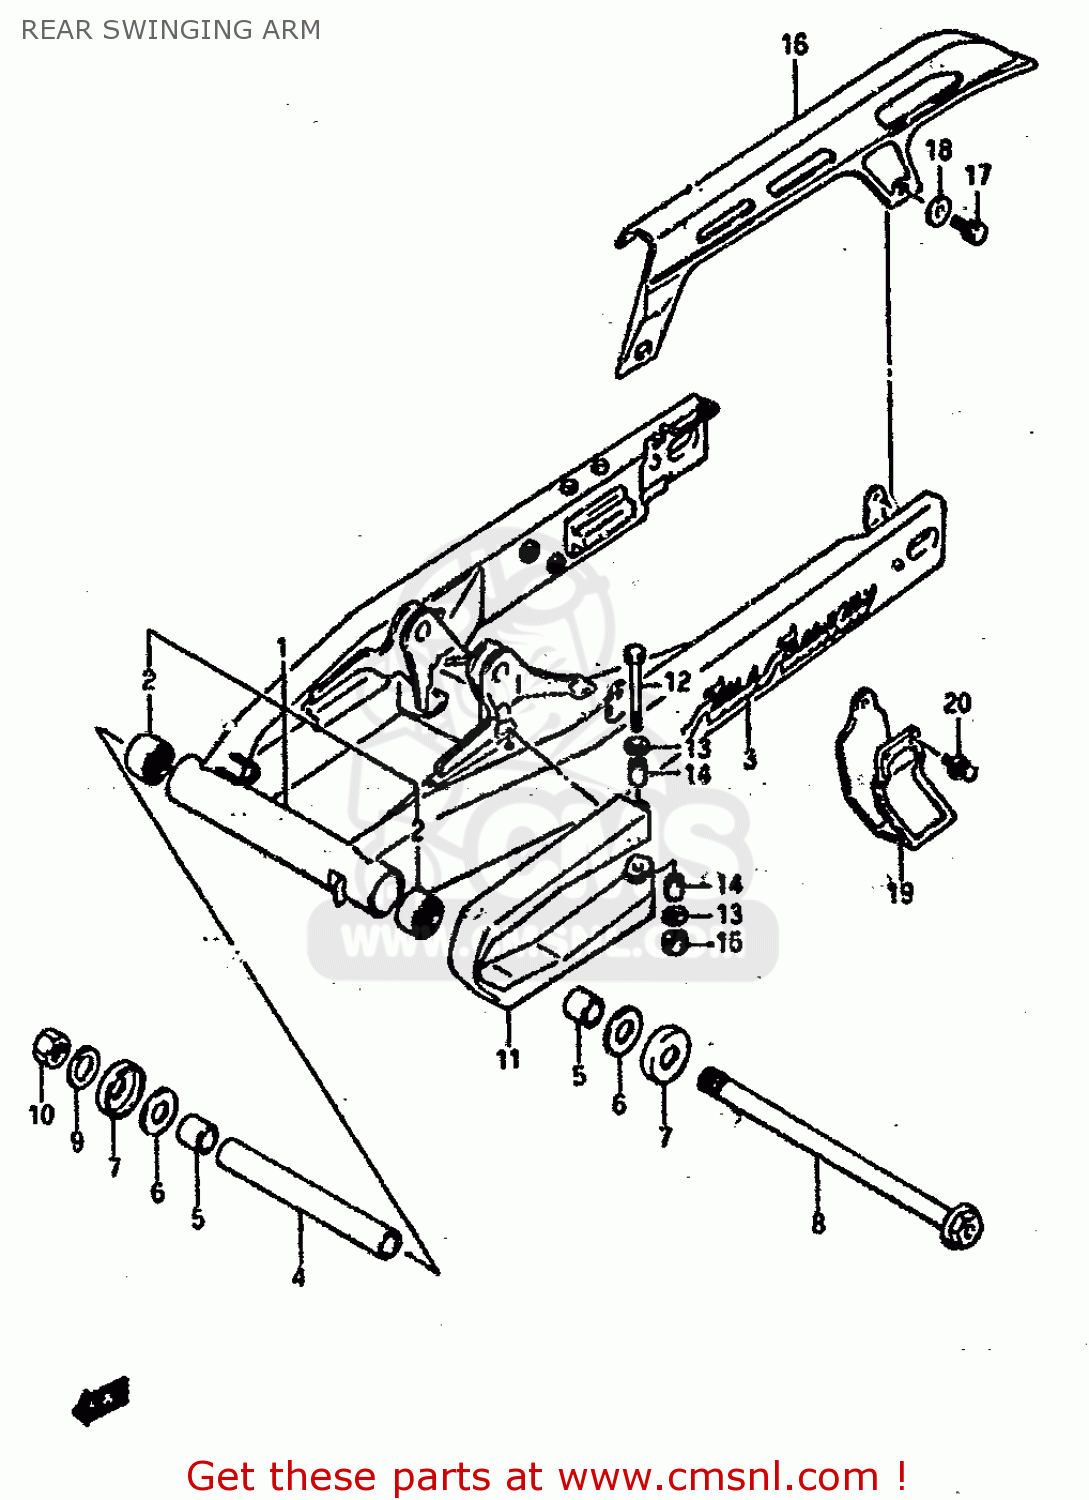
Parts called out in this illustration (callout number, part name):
1	SWINGING ARM ASSY,REAR (SILVER)
2	BEARING(22X29X20)
3	EMBLEM
4	SPACER,RR SWGARM PIVOT CTR
5	SPACER,RR SWGARM PIVOT
6	WASHER
7	SEAL,RR SWGARM PIVOT DUST
8	SHAFT,REAR SWING ARM
9	WASHER (BLACK)
10	NUT (BLACK)
11	BUFFER,CHAIN TOUCH DEFENSE
12	BOLT,TOUCH DEFENSE FTG
13	WASHER (5.5X14X1.2)
14	SPACER (6.6X9X6.5)
15	NUT
16	CASE,CHAIN
17	BOLT
18	WASHER
19	GUIDE,CHAIN
20	BOLT
